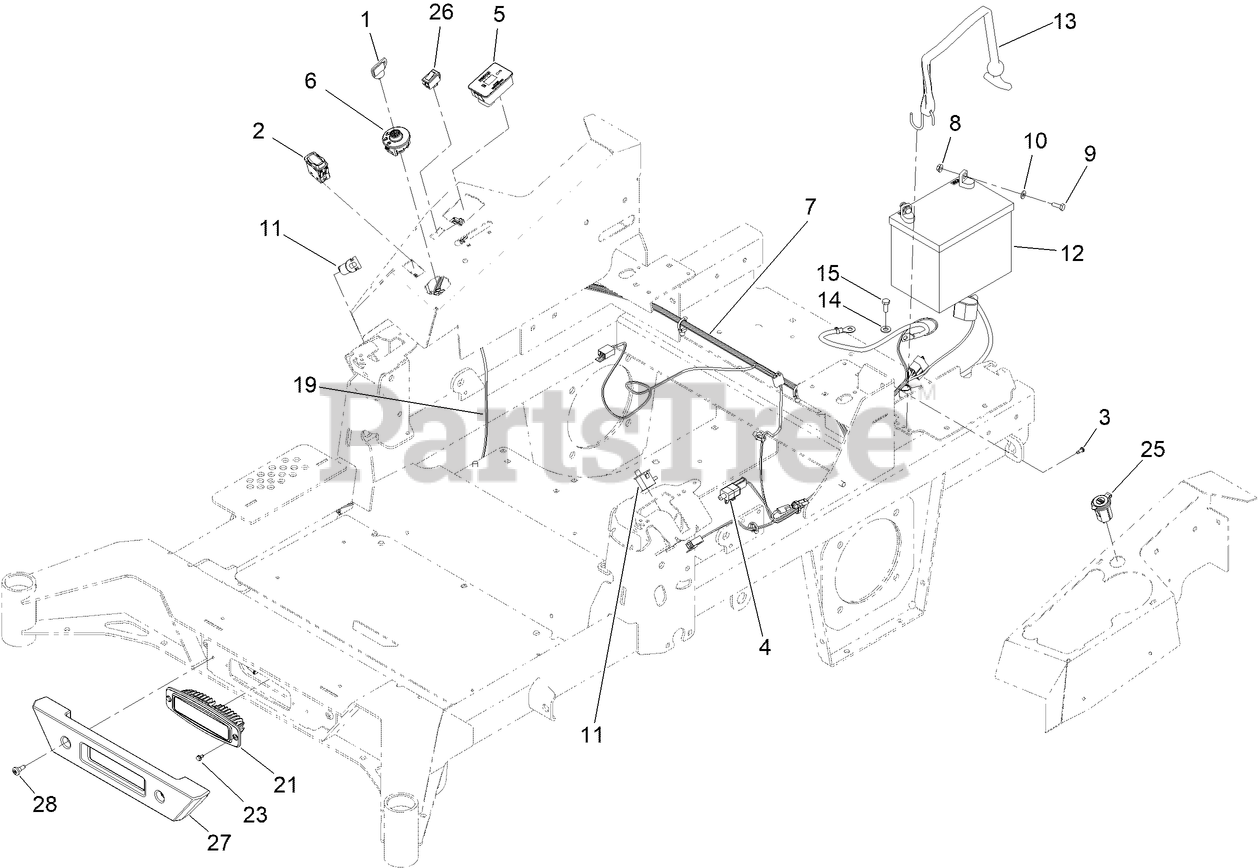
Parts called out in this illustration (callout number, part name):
1	KEYS-IGNITION (SPARE PAIR)
1	KEY-IGNITION
2	SWITCH-ROCKER, ON-NONE-ON
3	SCREW-HWH
4	SWITCH
5	MODULE ASM
6	SWITCH-IGNITION
7	HARNESS-WIRE
8	NUT-HF
9	SCREW-HH
10	WASHER-FLAT
11	SWITCH-BAIL
12	BATTERY-DRY
13	STRAP, BUNGEE
14	WASHER-PLAIN
15	SCREW-HH
19	HARNESS-WIRE, LIGHT KIT
21	MOUNT-FLUSH, LIGHT
23	SCREW-HWH
25	PORT-POWER, USB
26	SWITCH-ROCKER
27	BUMPER-FRONT
28	SCREW-SHOULDER
